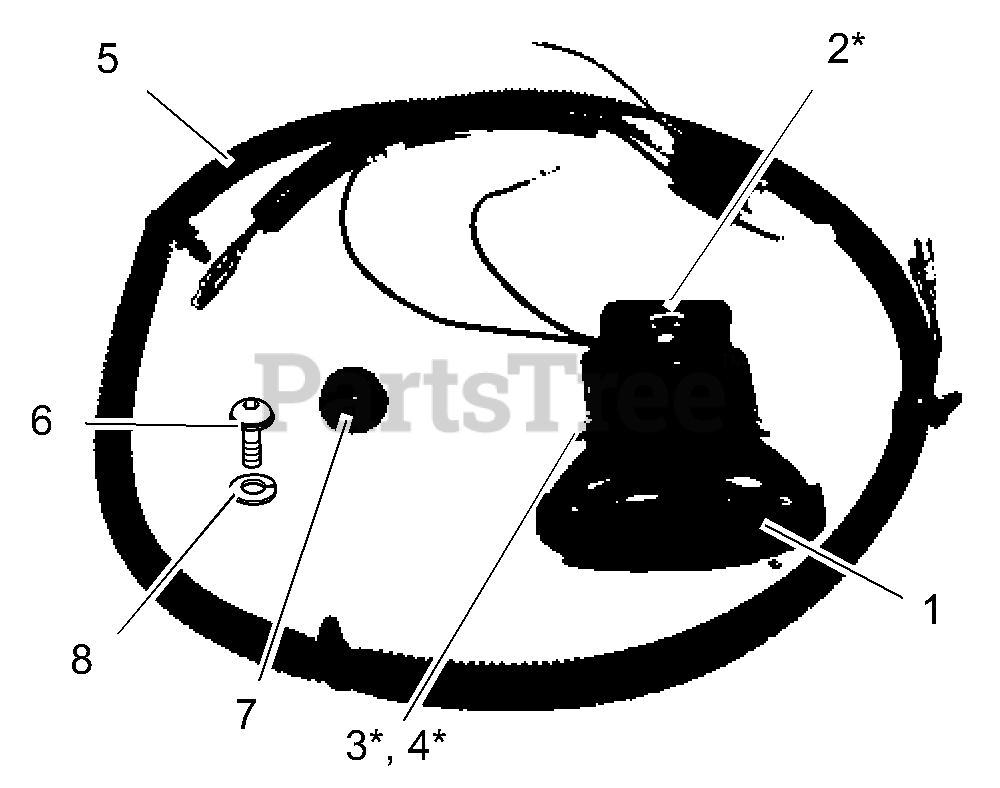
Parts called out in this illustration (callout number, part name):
1	Headlight
2	Light Bracket Weldment
3	4 mm x 1 mm Regular Cone Lock Washer
4	4 mm x .07 mm x 8 mm Socket Head Cap Screw
5	Light Harness
6	5/16"-18 x 1/2" Grade 5 Button Head Cap Screw
7	Rubber Grommet
8	5/16" Lock Washer
